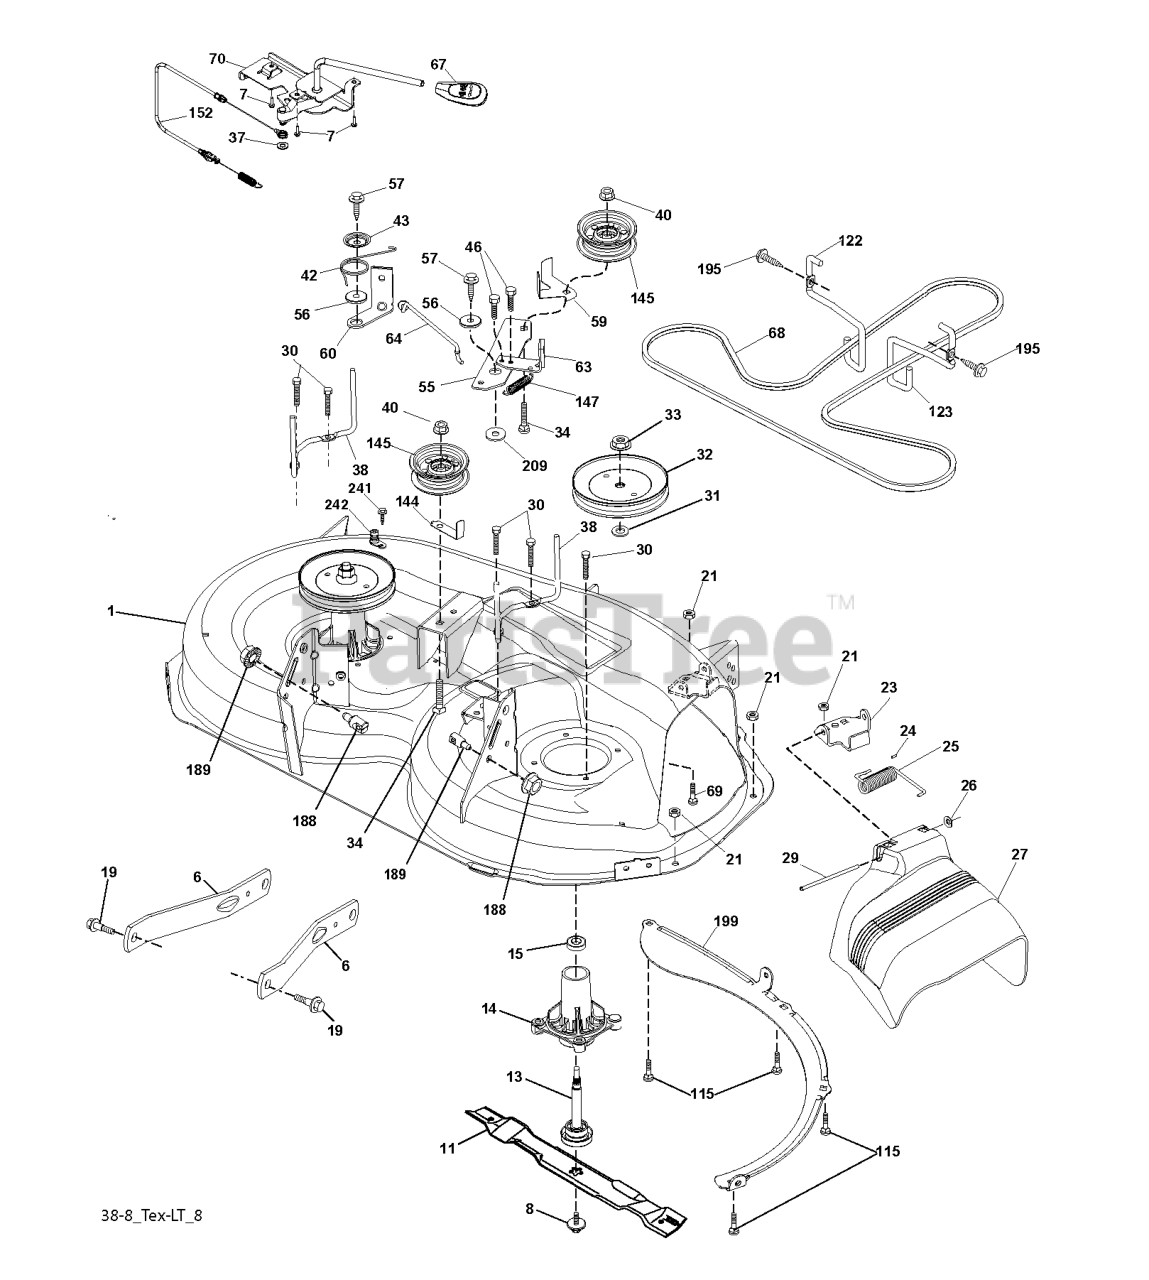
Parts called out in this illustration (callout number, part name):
6	ARM.SUSPENSION.MOWER.R
7	SCREW.#10 X 0.750.BOS
8	BOLT.WASHER.ASM.7/16-2
11	BLADE 38" PREMIUM
13	SHAFT.ASM.MDRL.N/GREASE.38
14	RP.HOUSING.MANDREL.4PT.
19	BOLT.SHOULDER
21	LOCKNUT
23	BRKT.DEFLECTOR.38"2005+
24	CAP-SLEEVE LT
25	SPRING.TORSION.DEFLECT
26	NUT PUSH M
27	SHIELD, DEFLECTOR
29	ROD.HINGE
30	SCREW, WASHER HEAD
31	WASHER.SPACER.MANDREL
32	PULLEY.MANDREL.5.0.PD.38"
33	NUT.FLANGE.LOCK.TOP
34	BOLT.3/8-16X1.50
37	WASHER
38	KEEPER BELT LH MANDREL
40	NUT LOCK FLG 3/8-16 UNC
42	SPRING.TORSION.BRAKE
43	SRPING.TORSION.RETAINE
46	SCREW.1/4-20X5/8
56	SPACER.RETAINER
57	SCREW 3/8-16X1
59	GUARD, BELT
60	ARM BRAKE MOWER RH 38"
63	RP ARM.BRAKE.MOWER.38"LH.TEX
64	LINK BRAKE
67	HANDLE.CLUTCH.CABLE.LT
69	BOLT
70	CLUTCH.ASM.MANUAL.LT.PRED
115	BOLT.CARR.5/16-18X5/8.SHORT
122	KEEPER BELT ENGINE LH
123	KEEPER BELT RH
144	KEEPER BELT
145	PULLEY.IDLER.48"PRIMARY
147	SPRING RETURN
152	CLUTCH CABLE
188	STUD.FASTNER.W/ANTI-ROTATE
189	NUT LOCK HEX FLANGE 5/16-18
195	SCREW, 3/8-16X3/4
199	BAFFLE.VORTEX.FRONT.38"
209	WASHER 12/32X2X10GA
241	SCREW.TT.#10-32X.5.3/8.FLANGE
242	PORT.WASHOUT
